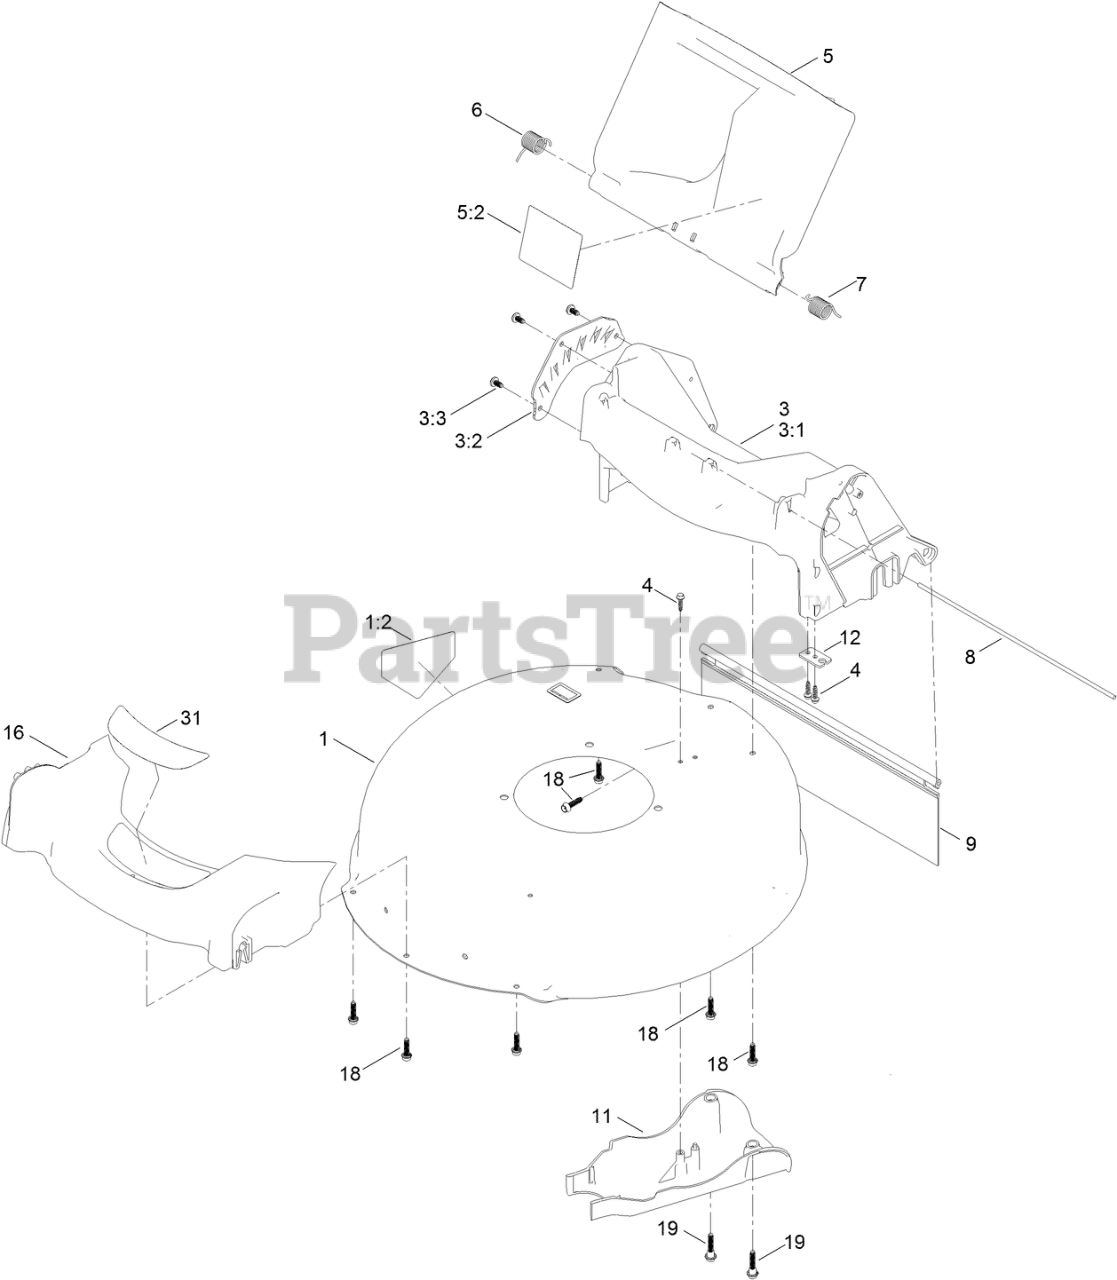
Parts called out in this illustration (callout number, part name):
1	HOUSING ASM
1:2	DECAL-DANGER
3	CHUTE ASM
3:1	CHUTE
3:3	SCREW-PLASTIC TPH
4	SCREW-HWH
5	REAR DEFLECTOR ASM
5:2	DECAL-WARNING
6	SPRING-TORSION
7	SPRING-TORSION
9	SHIELD-TRAILING
11	COVER-BELT
12	BRACKET-CABLE
18	SCREW-FLANGE, PLASTIC
19	SCREW-SHOULDER, HHF
31	DECAL-DECK
